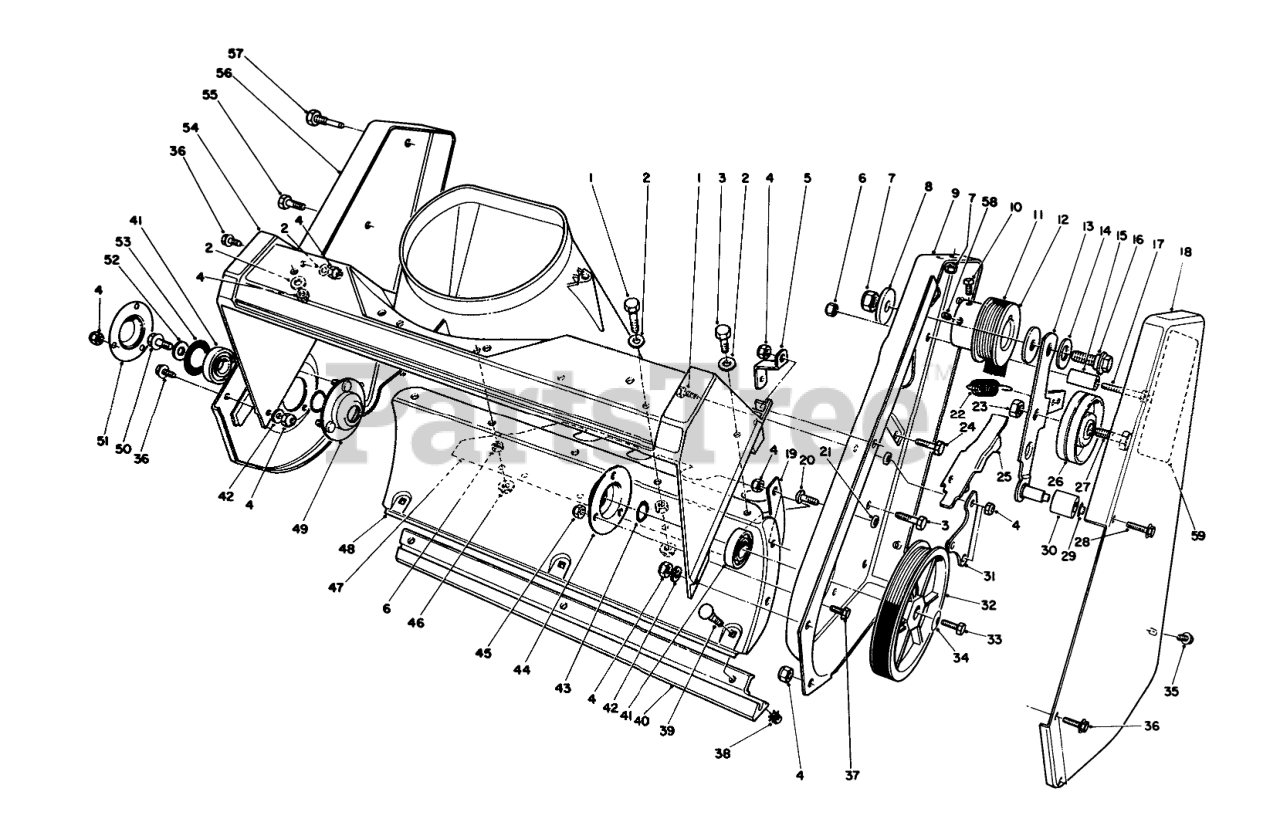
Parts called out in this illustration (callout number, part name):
1	SCREW-HH
2	WASHER-FLAT
3	SCREW-HH
4	NUT-LOCK, NI
5	BRACKET-HOUSING
6	NUT-HEX, SIDE DEFORM
7	NUT-LOCK, NI
8	WASHER-PIVOT
9	Sideplate-L.H.
10	SCREW-SQH
11	BELT - DRIVE
12	ENGINE PULLEY
13	Idler Arm Assembly (Incl. Ref. #29 & 30)
14	WASHER
15	SLEEVE-GUIDE, BELT
16	SCREW-SHOULDER
17	SCREW-HH
18	Cover-Drive
19	BRACKET-HOUSING, LOWER
20	SCREW-HSBH
21	SPACER-PLATE, PIVOT
22	SPRING-EXTENSION
23	NUT-LOCK, CONE
24	SCREW-HH
25	BRAKE-ARM
26	PULLEY-IDLER
27	SCREW-HH
28	SCREW-HWH, TAP
29	NUT-PUSH
30	ROLLER-BRAKE
31	PIVOT PLATE ASM
32	ROTOR PULLEY ASY
33	SCREW-HH
34	WASHER-BELLEVILLE
35	SCREW
36	SCREW-HWH
37	SCREW-SHH
38	NUT-KEPS
39	SCREW-CARR
40	SCRAPER
41	BEARING-BALL
42	WASHER-FLAT
43	WASHER-THRUST
44	FLANGE-BEARING
45	NUT-LOCK, NI
46	NUT-LOCK, HHF
47	Cover-Bottom
48	Housing-Lower
49	FLANGE-BEARING
50	SCREW-HHF
51	Trough
52	WASHER-FLAT
53	WASHER-RUBBER
54	HOUSING
55	SCREW-HH
56	Sideplate-RH
57	PIN-ROTOR
58	SCREW-HSH
59	DECAL
